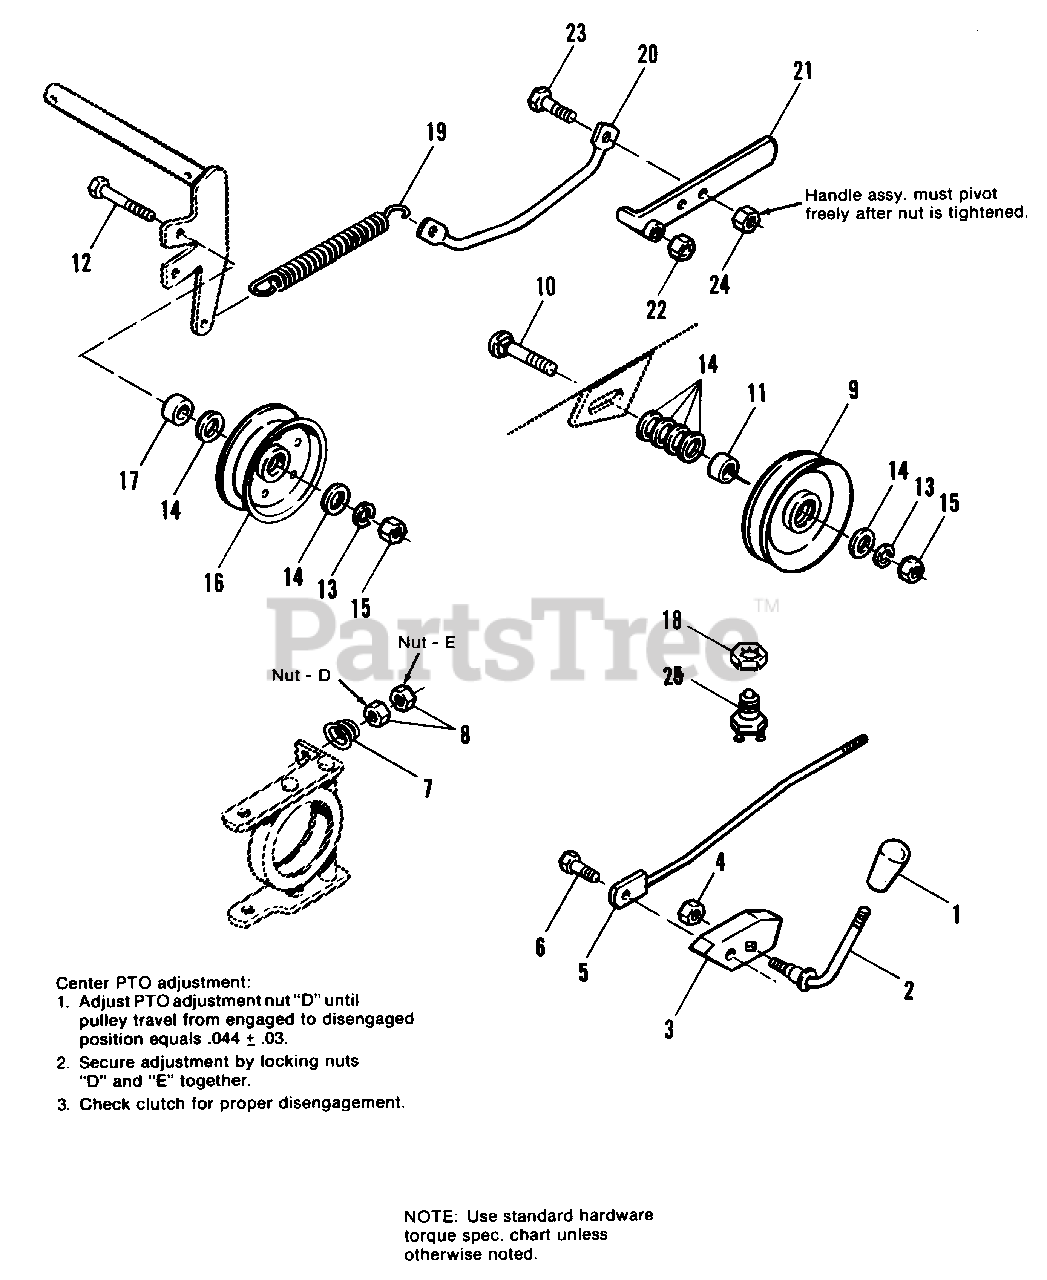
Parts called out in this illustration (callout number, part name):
1	KNOB
2	HANDLE, Clutch P.T.O.
4	LOCKNUT, Hex, 3/8-16
5	CONTROL ROD ASSY. (7116 & 7117 only)
5	CONTROL ROD ASSY. (7112 only)
6	CAPSCREW, Special
7	SPRING (7116 & 7117 only)
7	SPRING (7112 only)
8	NUT, Hex, Full, 5/16-18
9	PULLEY ASSY., W/Bearing
10	BOLT, Carriage. 3/8-16 x 1-1/2
12	CAPSCREW, Hex Hd., 3/8-16 x 2
13	LOCKWASHER, 3/8
14	WASHER, 5/16
15	NUT, Hex, Full, 3/8-16
16	PULLEY, Idler
18	NUT, Pal
19	SPRING. Tension
20	ROD, Tension
21	HANDLE ASSY.
22	LOCKNUT, Hex, 7/16-14
23	CAPSCREW, Hex Hd., 5/16-18 x 3/4
24	LOCKNUT, Hex, 5/16-18
25	SWITCH, Interlock
